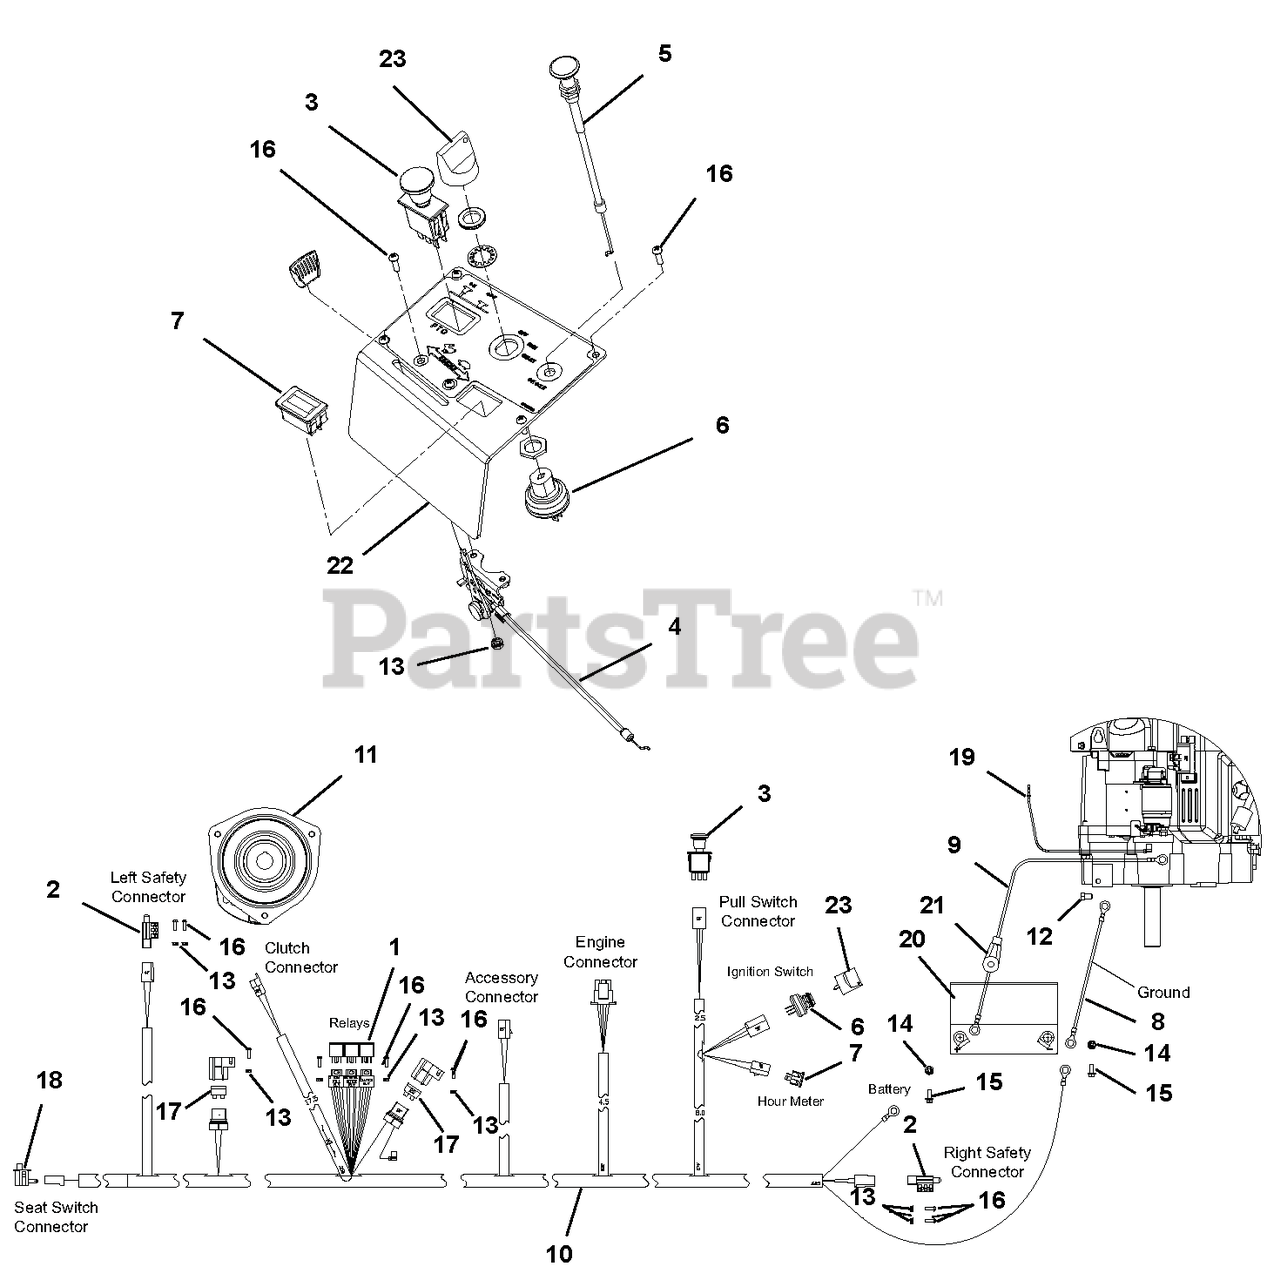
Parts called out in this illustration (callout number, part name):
1	RELAY, ISO MINI ELEC.
2	SWITCH, PLUNGER DP - N.O.-N.C.
3	SWITCH, PTO ENGAGEMENT
3	SWITCH, CLUTCH (WITH GRAPHIC)
4	THROTLE CABLE, 40" WITH DETENT
4	CABLE, PRO-CONTROL
5	CABLE, CHOKE 48.0"
5	CABLE, PRO-CONTROL THROTTLE
6	SWITCH, IGNITION
7	METER, HOUR - LCD ALT. (ENM)
7	METER, HOUR W/MAINTENANCE
8	CABLE, BATTERY - 25" GROUND
9	CABLE, BATTERY - 42" POSITIVE
10	WIRE HARNESS
11	CLUTCH, ELECT-OGURA, GT3.5
12	BOLT, M8X1.25X14 HEX 8.8 Y
13	NUT, 10-24 KEPS Y
13	@NUT-LK-NYL 10-24 W/INSRT YWZC
14	@NUT-SPNLK-FLG .25-20 YWZC
15	SCR-HEX-FLNG .25-20 X .625 G2
16	SCREW, 10-24X.625 PAN PHL MACY
16	SCR-MCH 10-24X.38 HWHSTAINLESS
16	@SCR-MCH 10-24X.50 HWH YWZC
17	FUSE, 20 AMP BLADE S/O
18	SWITCH- SNAP MTG N.O.
19	LEAD - STARTER SOLENOID
20	BATTERY, 12V-U1-CCA400MIN
21	BOOT, BATTERY TERMINAL-RED
22	PLATE, CONTROL PANEL
22	PANEL, CONTROL
23	KEY, W/ SHIELD
